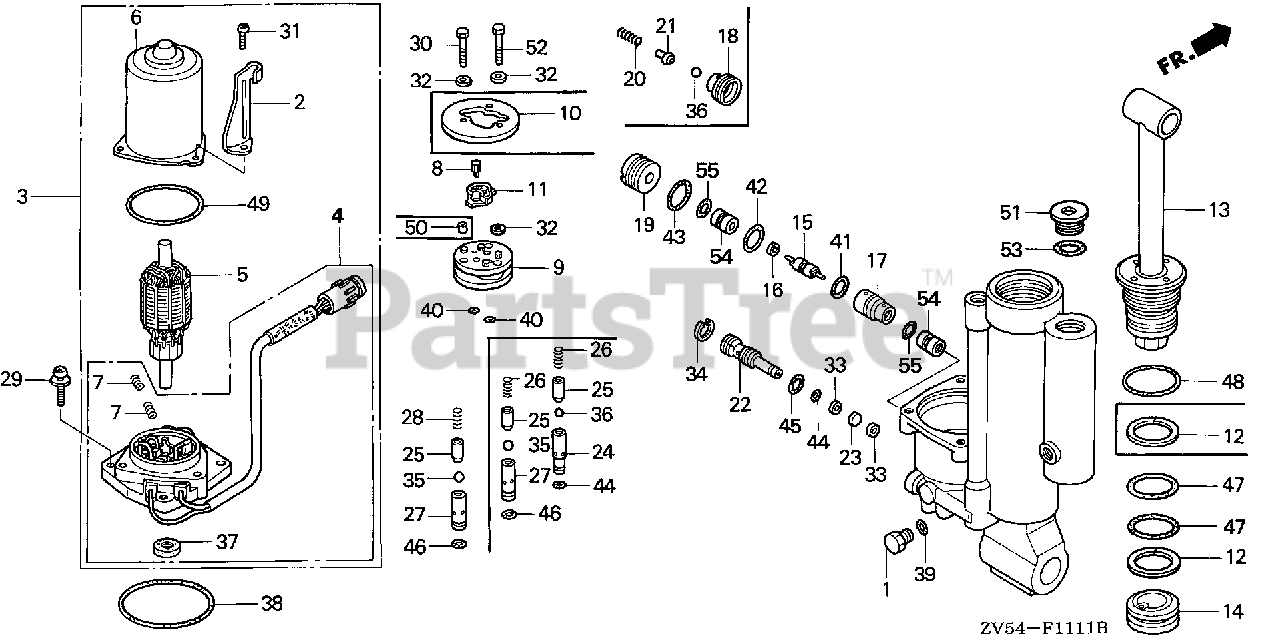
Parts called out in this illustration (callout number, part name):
1	CAP, OIL HOLE
2	CLAMP, WIRE
3	MOTOR ASSY., POWER TILT
4	BRACKET ASSY.
7	SPRING, MOTOR
8	JOINT, DRIVE
10	HOLDER, VALVE
13	ROD, PISTON
14	PISTON, FREE
15	SPOOL, VALVE
16	RING, BACK-UP
18	SEAT D, VALVE
20	SPRING, CHECK VALVE
21	GUIDE B, SPRING
22	VALVE, MANUAL
23	SEAT, PLATE
24	SEAT, VALVE
25	GUIDE, SPRING
26	SPRING, VALVE
27	SEAT B, VALVE
28	SPRING B, VALVE
29	SCREW-WASHER
30	BOLT, HEX. (5X30)
31	SCREW, PAN (5X16)
32	WASHER, PLAIN
33	WASHER, SEAL
34	CIRCLIP (INNER)
35	BALL, STEEL
36	BALL, STEEL
49	O-RING
52	BOLT, HEX. (5X30)
